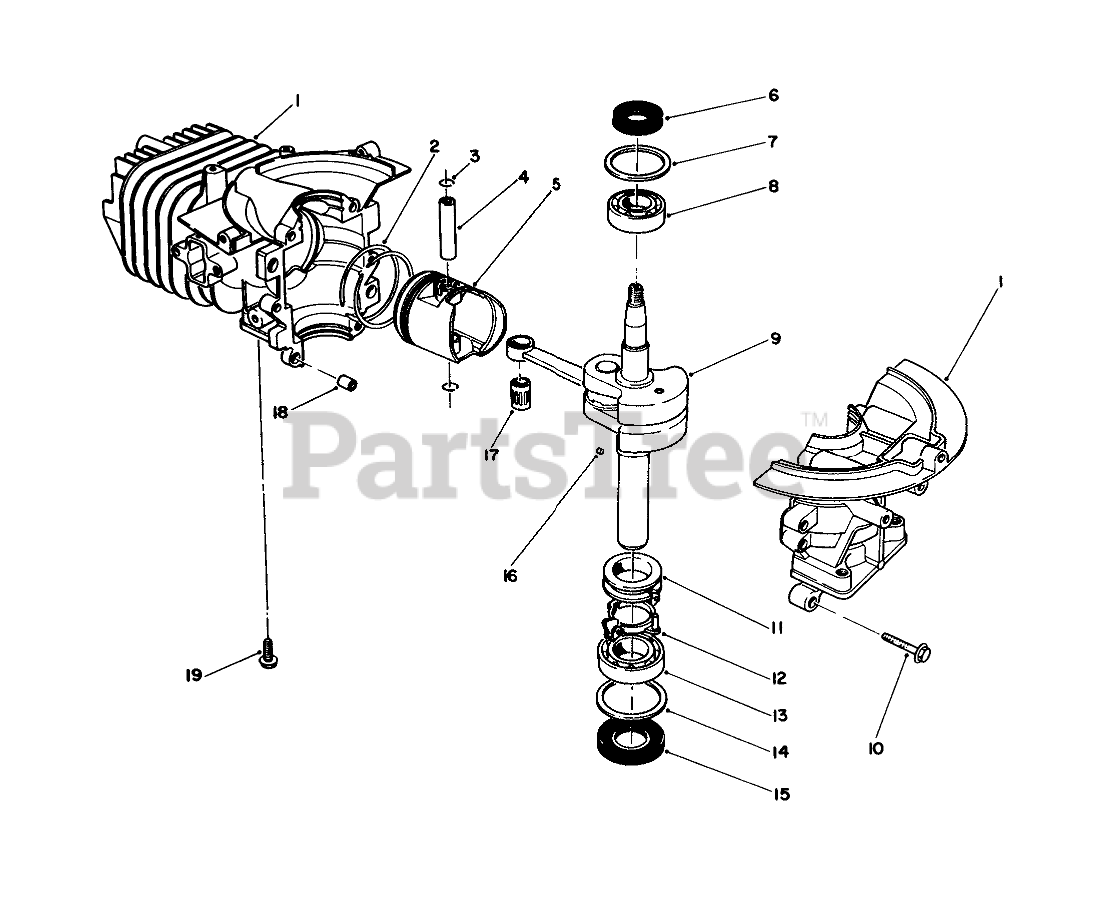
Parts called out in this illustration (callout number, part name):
1	CYL/CRANKCASE ASM
2	RING SET
4	PIN-PISTON
5	Piston
6	OIL SEAL
7	WASHER-UPPER
8	BEARING-UPPER
9	CRANKSHAFT ASM
11	SPACER
12	BRACKET
13	LOWER BRG
14	WASHER-LOWER
15	SEAL-OIL
17	BEARING
